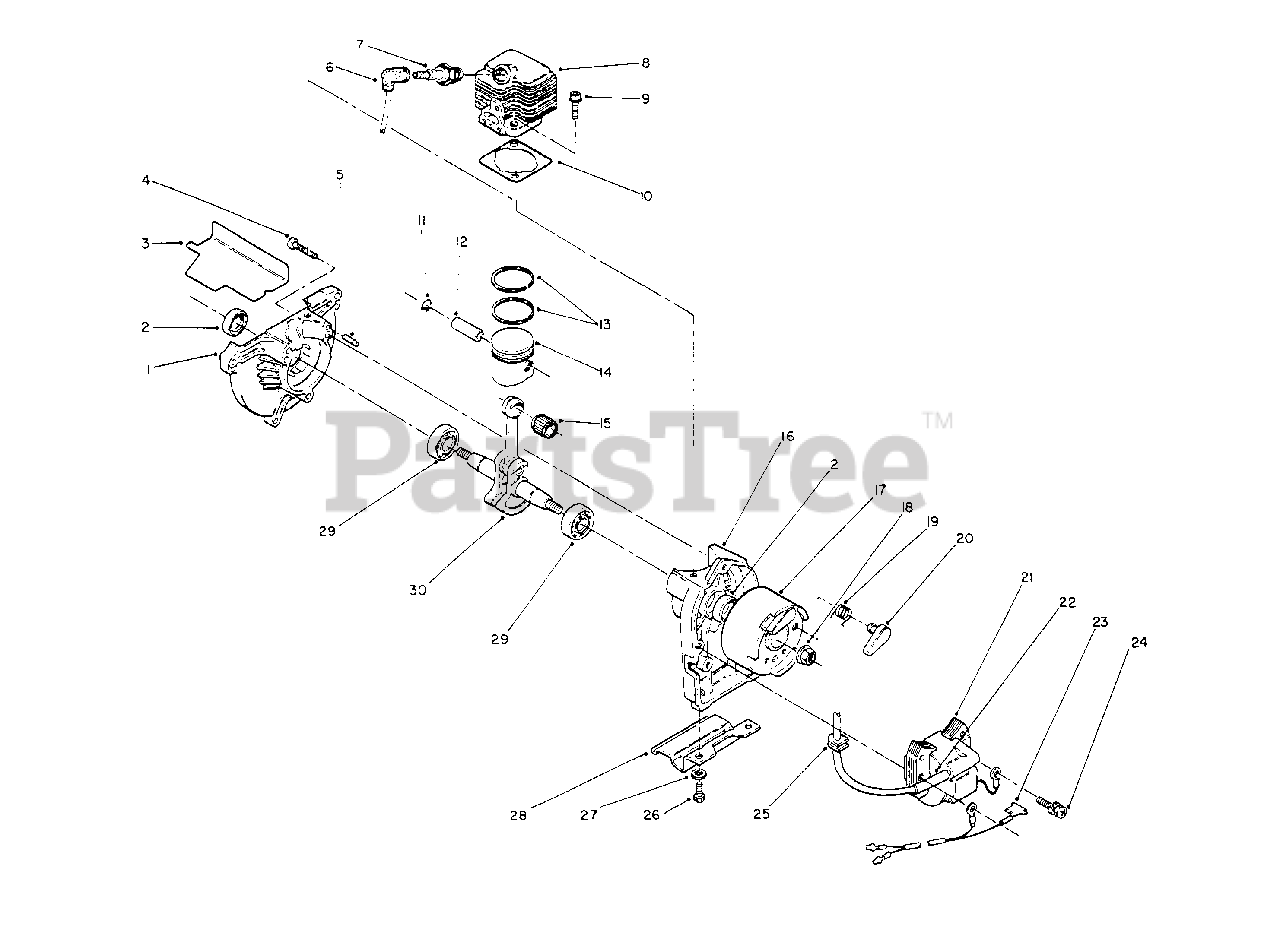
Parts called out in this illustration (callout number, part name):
1	Case-Drive
2	Seal-Oil
3	Gasket-Baffle
4	Screw-Pan Hd.
5	Pin-Dowel
6	Boot-Plug
7	Plug-Spark
8	Cylinder Head
9	Bolt-Cylinder Head
10	Gasket-Cylinder Head
11	Clip-Piston Pin
12	Pin-Piston
13	Set-Piston Ring
14	Piston Ass'y (Incl. Ref. #12)
15	Bearing-Needle
16	Case-Starter
17	Flywheel (Incl. Ref. #19 & 20)
18	Nut-Conical
19	Spring-Return
21	Coil-Ignition
23	Wire Lead Assembly
24	Bolt/Washer
27	Washer-Lock
29	Bearing-Main
30	Crankshaft Assembly
